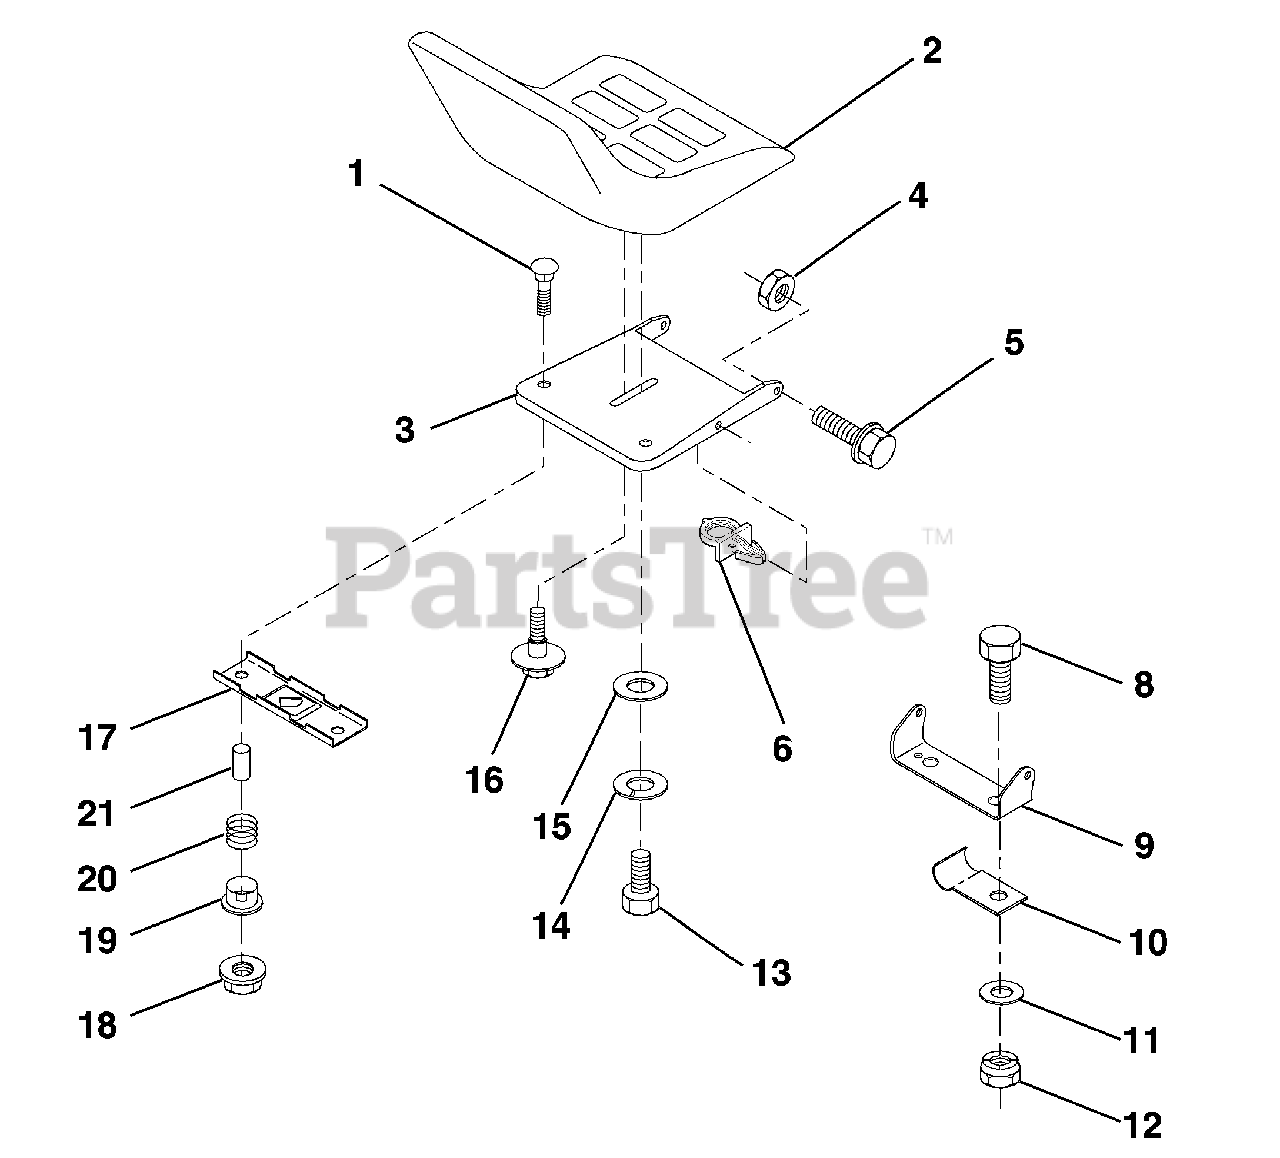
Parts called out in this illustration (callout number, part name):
1	Bolt, Carriage 1/4-20 x 1-1/2
2	Seat
3	Pan, Seat
4	Locknut, Hex w/Ins 5/16-18
5	Bolt, Shoulder 5/16-18 UNC
6	Clip, Push-in
8	Bolt, Fin Hex 3/8-16 UNC x 1
9	Bracket, Pivot Seat
10	Clip, Insulated
11	Washer 12/32 x 2 x 10 Ga.
12	Nut, Lock Hex w/Wsh 3/8-16
13	Bolt Hex 1/2-13 x 7/8
14	Washer Lock Hvy. Hlicl Spring 1/2
15	Washer, 17/32 x 1-3/16 x 12 Ga.
16	Bolt, Shoulder
17	Bracket, Switch, Mounting
18	Nut, Hex Large Flange Lock
19	Bushing, Snap
20	Spring, Compression
21	Spacer, Split 28 Id. x .88 Lg.
